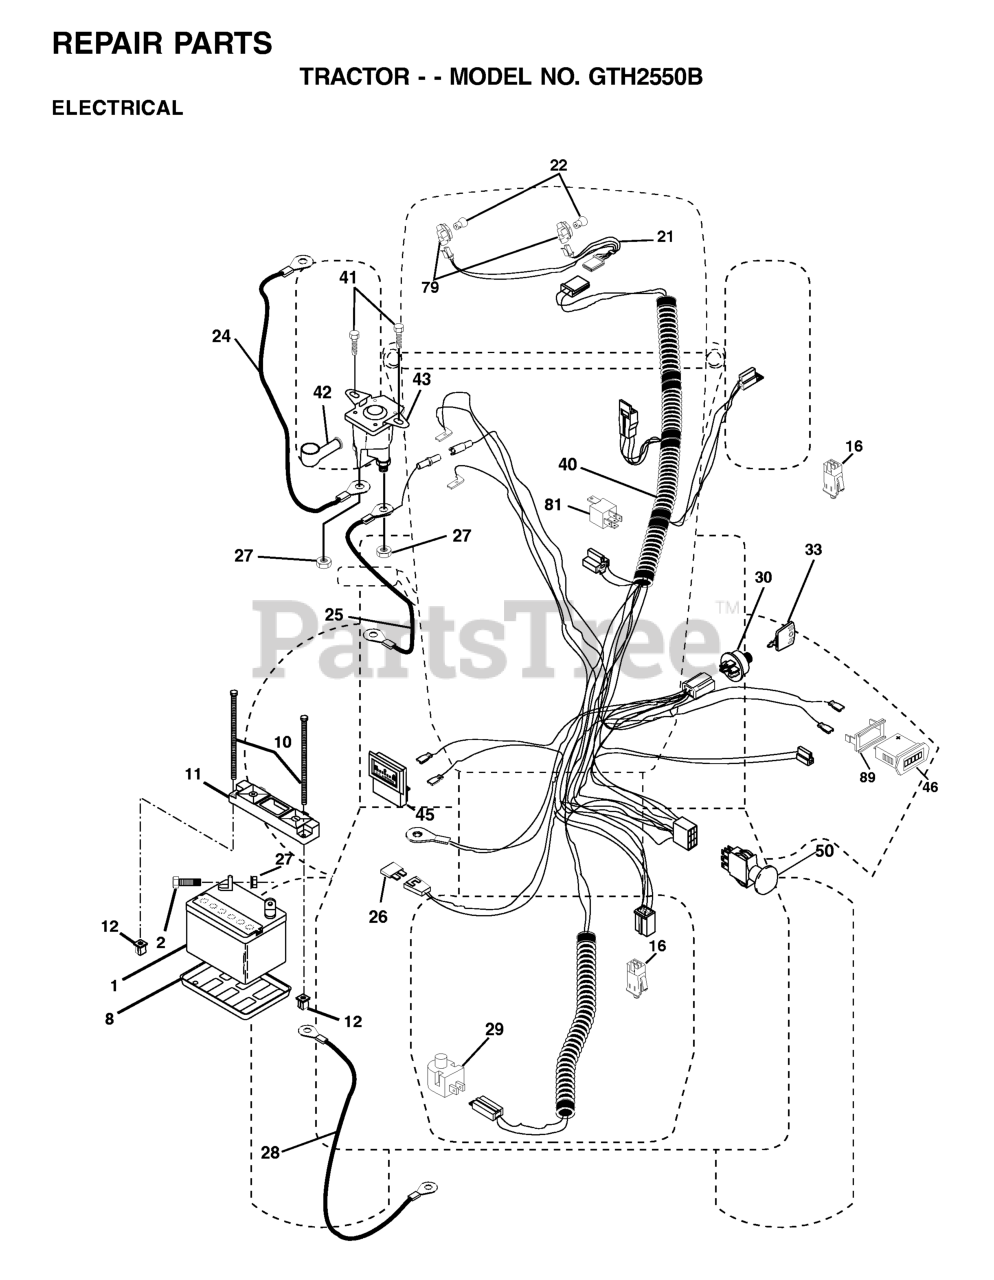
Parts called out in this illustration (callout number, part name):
1	BATTERY
2	BOLT.HEX.1/4.X.3/4.DICHROMATE
8	BATTERY TRAY T
10	BOLT 1/4-20 X 7.5
11	BATTERY HOLDDOWN FRONT MOUNT
12	NUT, PUSH NYLON 1/4" BATTERY
16	SWITCH INTERLOCK
21	HARNESS ASM LIGHT
24	CABLE-BATTERY YTV
25	CABLE, BATTERY
27	NUT
28	CABLE, GROUND
29	PLUNGER SWITCH (COLOR:OLIVE)
30	IGNITION SWITCH
33	KEY MLD GEN DELTA
40	HARNESS, IGNITION
41	SCREW
42	TERMINAL COVER
43	SOLENOID
46	HOUR METER
50	RP.PTO.SWITCH.8 TERMINAL.BLACK
79	BULBHOLDER ASM
81	RELAY.ASSY.T
89	BRACKET SNAP-IN HOURMETER
